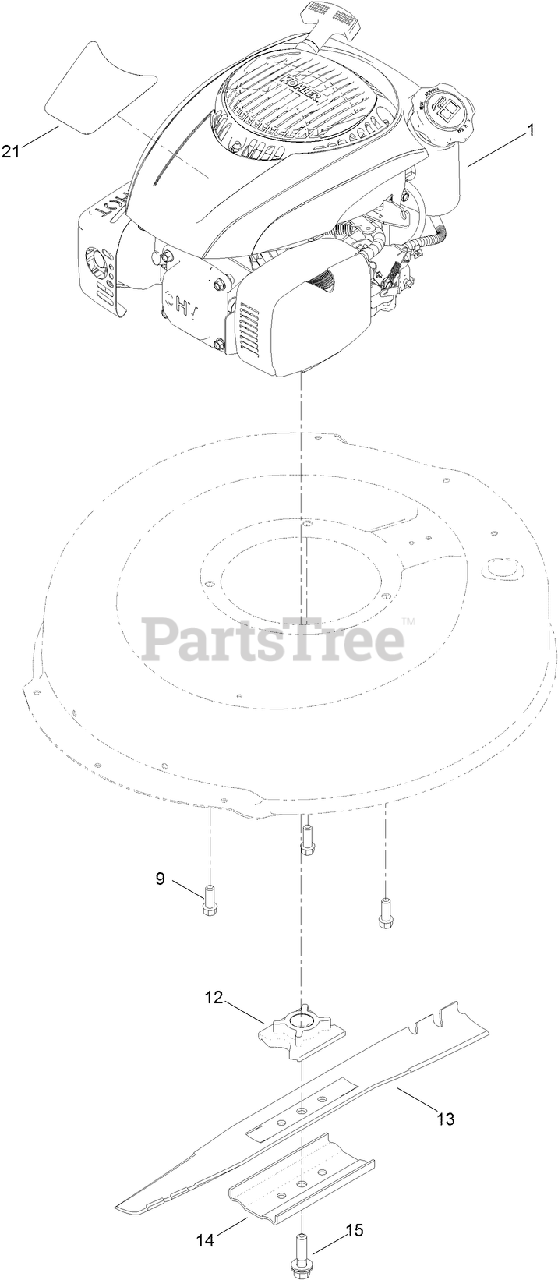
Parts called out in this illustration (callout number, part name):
9	SCREW-TAPTITE
12	RETAINER-BLADE
14	SUPPORT-BLADE
15	BOLT-BLADE
